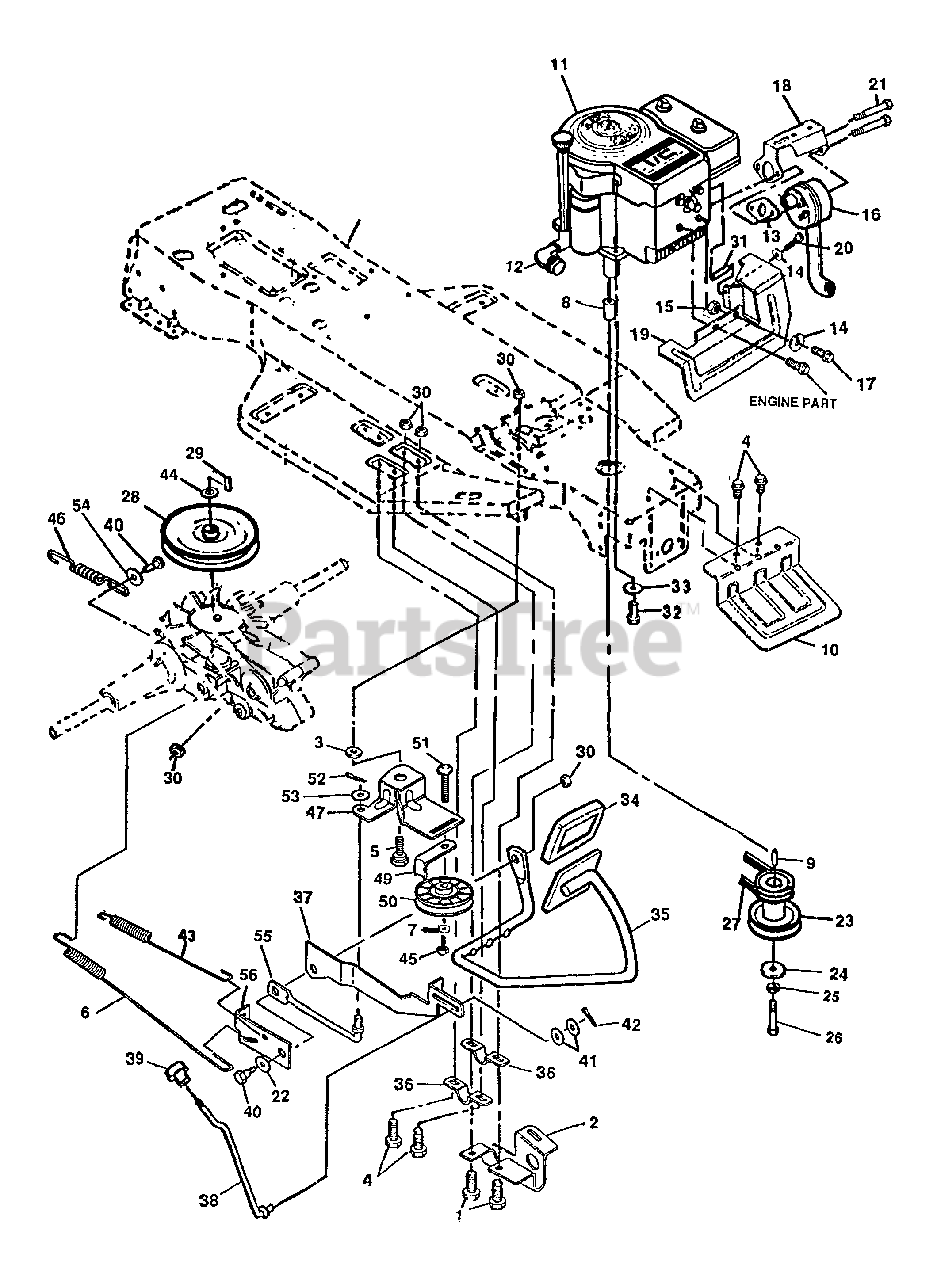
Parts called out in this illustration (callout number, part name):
1	Screw, 5/16-18 x 3/4 In.
2	Front Hanger Bracket
3	Flatwasher
4	Screw, Hx Hd, Wshr Tap, 5/16-18 x 1/2 In.
5	Shoulder Bolt, 5/16-18
6	Spring, Brake, Hydro
7	Lockwasher
8	Spacer, Engine Pulley
9	Key, Square, 1/4
10	Deflector, Exhaust
11	Engine 12.5 Horsepower B&S
12	Elbow, 900, 3/8 In.
13	Gasket, Muffler
14	Washer, Split Lock
15	Nut, Hex 5/16-18 Thd.
16	Muffler, Round 5" Diameter
17	Screw, Wa Tap, 1/4-20 x 7/8 In.
18	Heat Shield, Carburetor
19	Heat Shield, Engine
20	Screw, Hex Hd, 1/4-20 x 3-1/2 In.
21	Bolt, Shoulder, 5/16-18 x 4-1/3 In.
22	Wave Washer
23	Pulley, Engine
24	Washer, Pilot
25	Washer, Split, Lock 7/8 In.
26	Screw, Hx Hd, 7/16-20 X 5 In.
29	Key, Woodruff, #606
30	Nut, Hex, Ctrlk, 5/16-18 Thd.
31	Spacer, Heat Shields
32	Screw, Hex Hd Tap, 3/8-16 x 1-1/4 In.
33	Washer, 3/8 In.
34	Pad, Clutch/Brake, Molded
35	Assembly, Clutch/Brake Arm
36	Bracket, Clutch/Brake Arm
37	Lever, Park Brake
38	Rod, Parking Brake
39	Knob, Parking Brake
40	Shoulder Bolt, 5/16-18 Thd.
41	Washer, 9/16 In.
42	Cotter Pin
43	Spring, Clutch
44	Retaining Ring
45	Nut, Flange, 3/8-16 Thd.
46	Spring, Brake
47	Arm, Idler
48	Shoulder Bolt, 3/8-16 Thd.
49	Belt Retainer
51	Carriage Bolt, 3/8-16 x 1-1/2 In.
52	Hair Pin
53	Flatwasher, 13/32 In.
54	Flatwasher
55	Clutch Rod
56	Brake Bracket, Neutral
